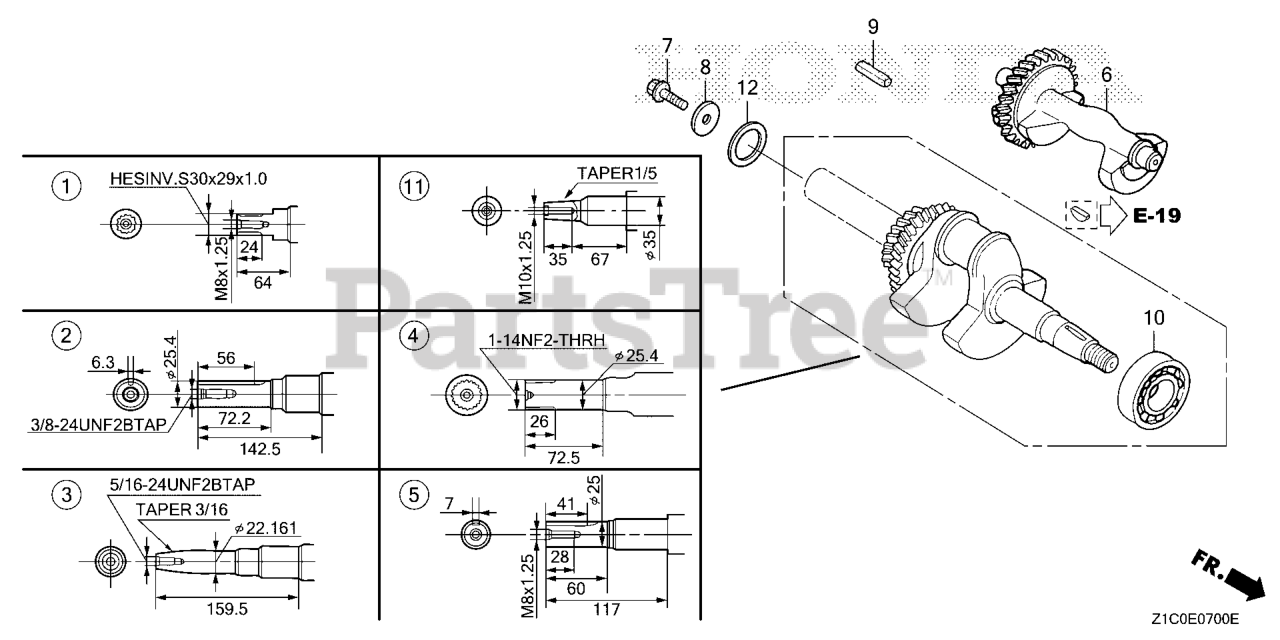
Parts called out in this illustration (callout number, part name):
5	CRANKSHAFT
6	WEIGHT, BALANCER
9	KEY (7X7X33)
10	BEARING, RADIAL BALL (6207SH)
